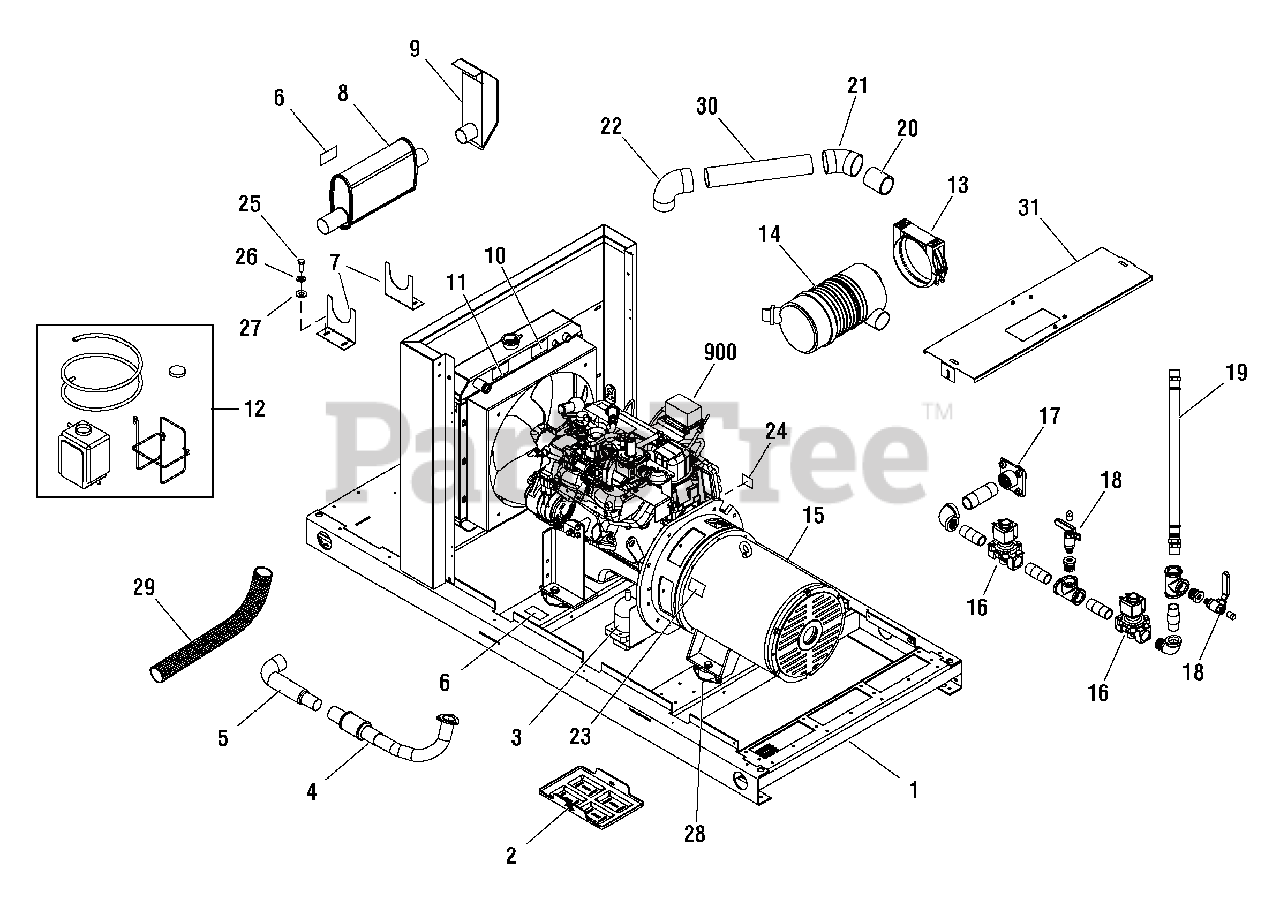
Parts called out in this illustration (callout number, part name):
1	BASE
6	DECAL
7	BRACKET, Muffler
8	MUFFLER
9	DIFFUSER
11	DECAL
12	BOTTLE, Overflow
24	DECAL
25	* CAPSCREW, Hex Head, 1/4-20 x 3/4
26	* WASHER, Lock, 1/4-M6
27	* WASHER, 1/4
28	MOUNT, Vibration
900	** ENGINE
